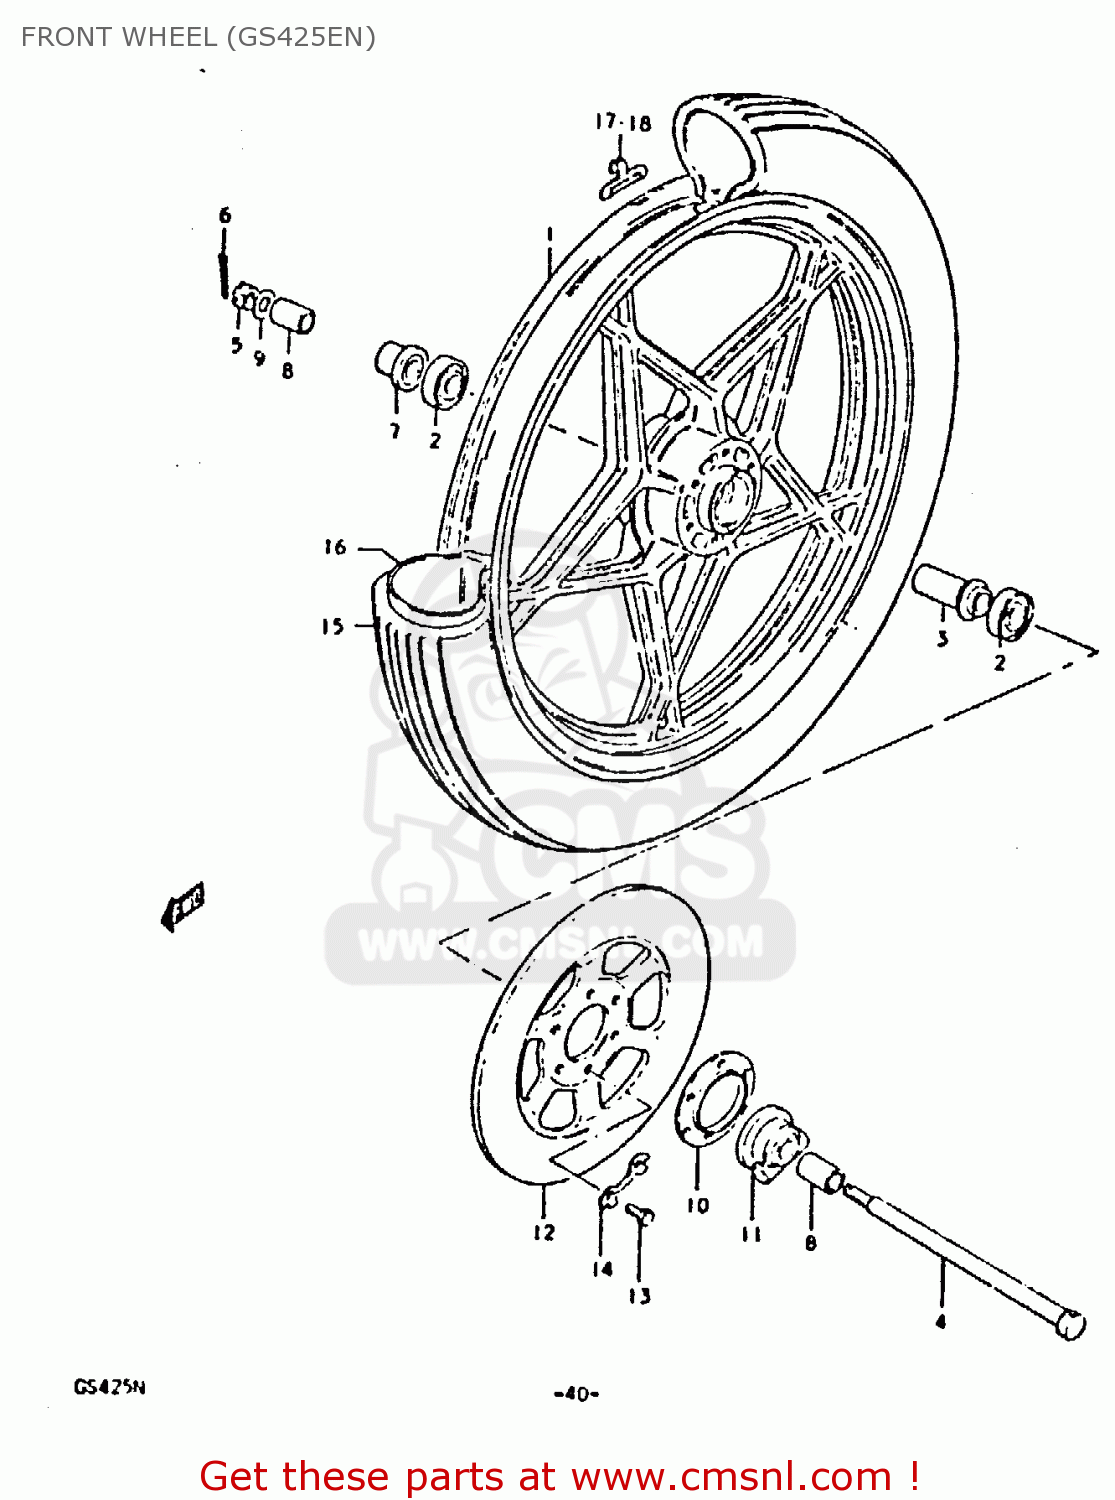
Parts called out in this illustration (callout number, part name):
1	WHEEL (DARK GRAY)
2	BEARING
3	SPACER(15.3X21.7X63)
4	AXLE,FRONT
5	NUT 12MM
6	COTTER PIN
7	SPACER,FR AXLE,R
8	SPACER(15X22X30)
9	WASHER
10	DUST SEAL,SPEEDOMETER GEAR BOX
11	BOX ASSY,SPEEDOMETER GEAR
12	DISC,REAR BRAKE
13	BOLT(8X25)
14	WASHER
15	TIRE,FRONT
16	TUBE,INNER
17	BALANCER,WHEEL
18	BALANCER,WHEEL
